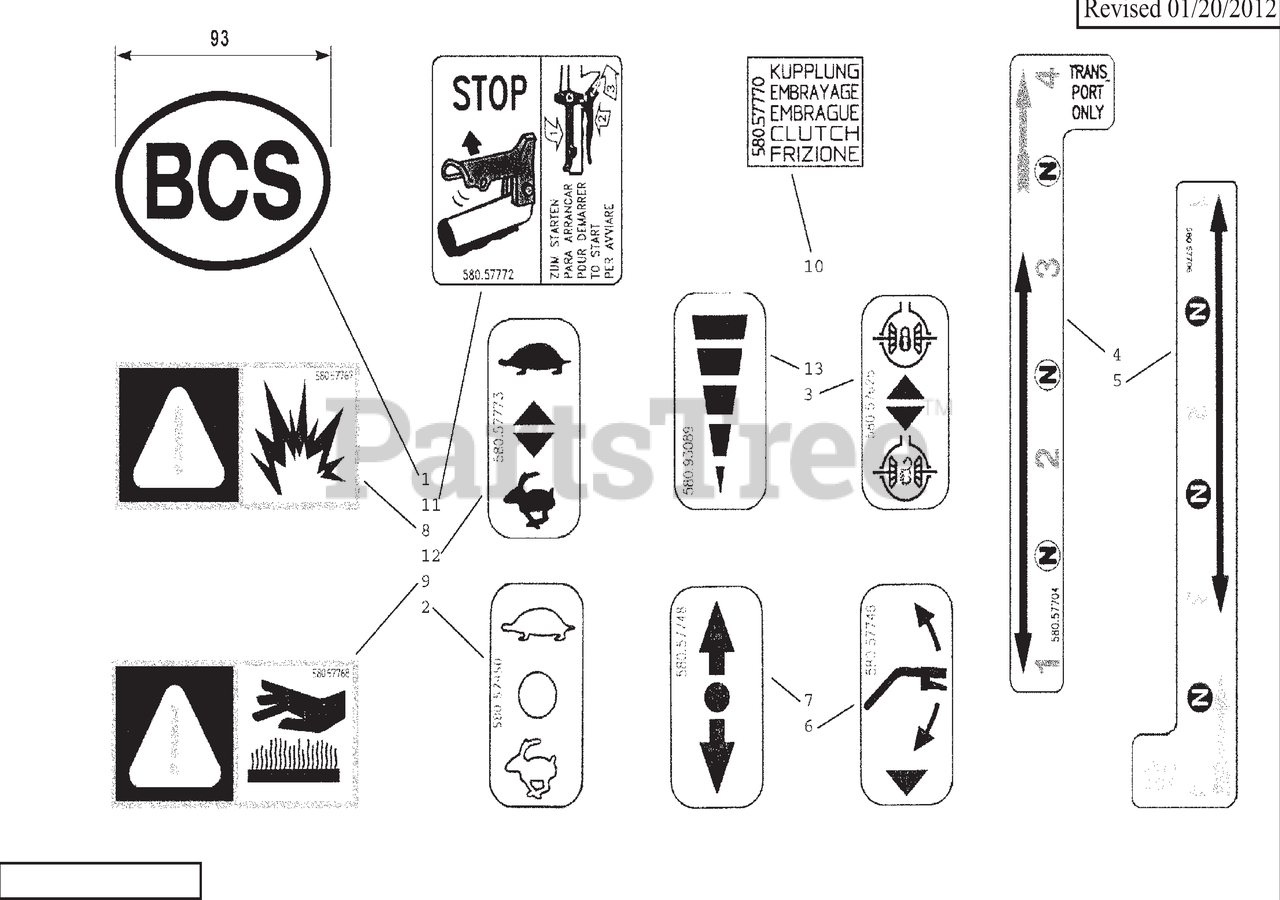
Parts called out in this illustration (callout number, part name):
1	DECAL, BCS
2	DECAL, THROTTLE (VERSION 1)
3	DECAL, DIFFERENTIAL
4	DECAL, SHIFT SELECT (853 ONLY)
5	DECAL, GEAR SELECT (852 ONLY)
6	DECAL, HANDLE HEIGHT ADJUST
7	DECAL, FORWARD / REVERSE
8	DECAL, CAUTION EXPLOSIVE
9	DECAL, CAUTION HOT
10	DECAL, CLUTCH
11	DECAL, STOP LEVER
12	DECAL, THROTTLE
13	DECAL
